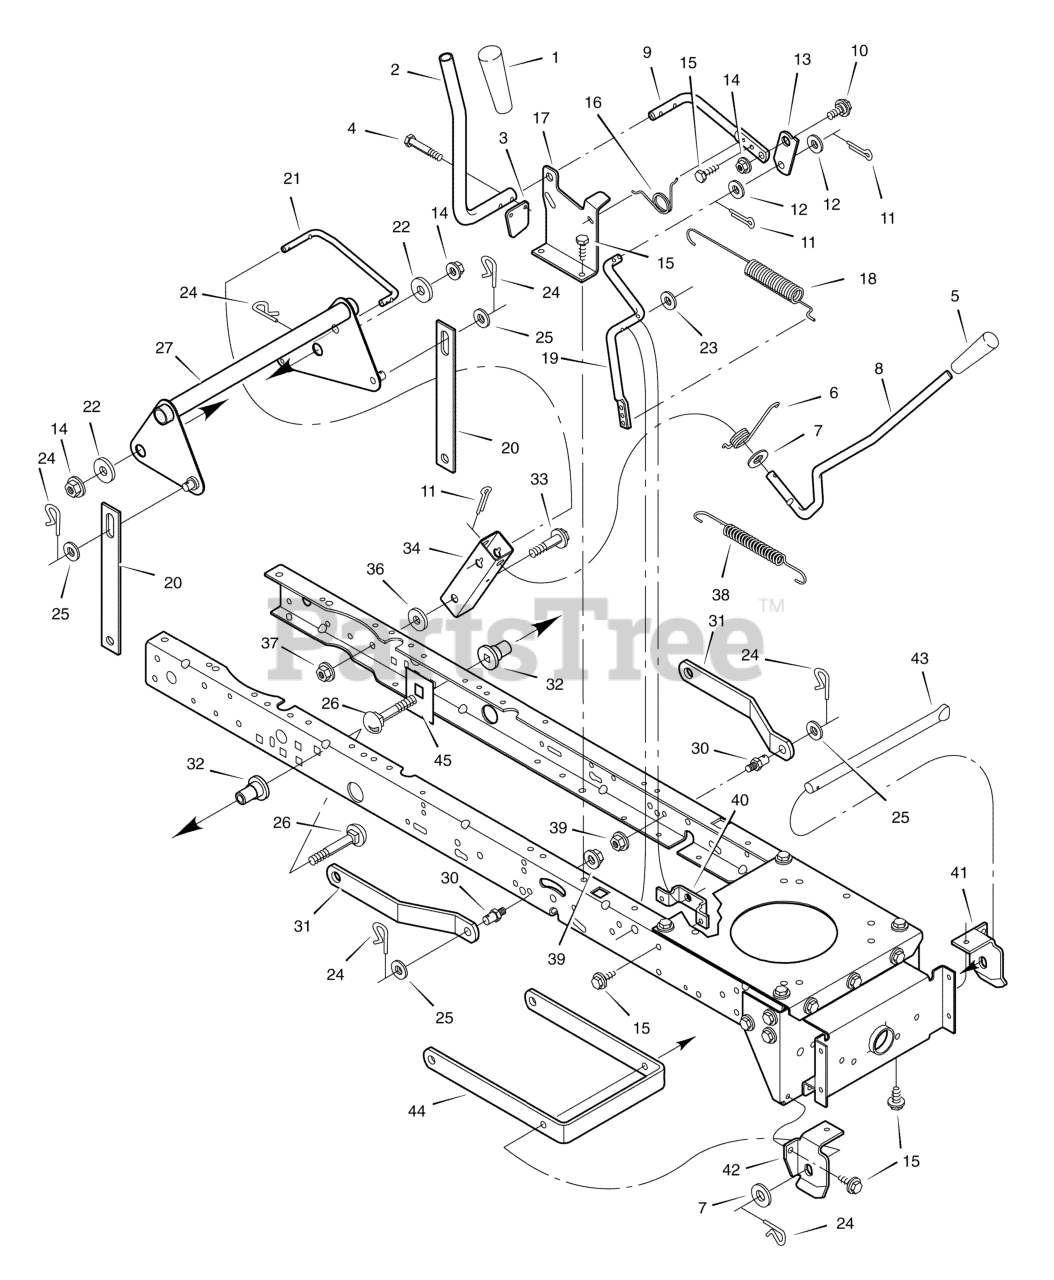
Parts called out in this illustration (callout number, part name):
1	GRIP
2	HANDLE, PTO
3	PAD, Switch
4	SCREW, Hex
5	GRIP
8	HANDLE, Lift
9	LEVER, PTO
10	BOLT, Shoulder
11	PIN, Cotter
13	LINK, PTO
14	NUT, Flange
17	BRACKET, PTO
18	SPRING, PTO
19	CRANK, PTO
20	LINK, Lift
21	LINK, Lift Handle
24	PIN, Hair
26	BOLT, Carriage
27	LEVER ASSEMBLY, Lift
30	PIN
31	BRACKET, Rear Suspension
32	SPACER, Lifter
33	BOLT, Shoulder
34	BRACKET, Pivot
37	NUT, Flange
39	NUT, Flange
40	BRACKET, PTO
41	HANGER, Left Deck
42	HANGER, Right Deck
43	ROD, Hanger
44	BRACKET, Suspension
45	PLATE, Stiffening
